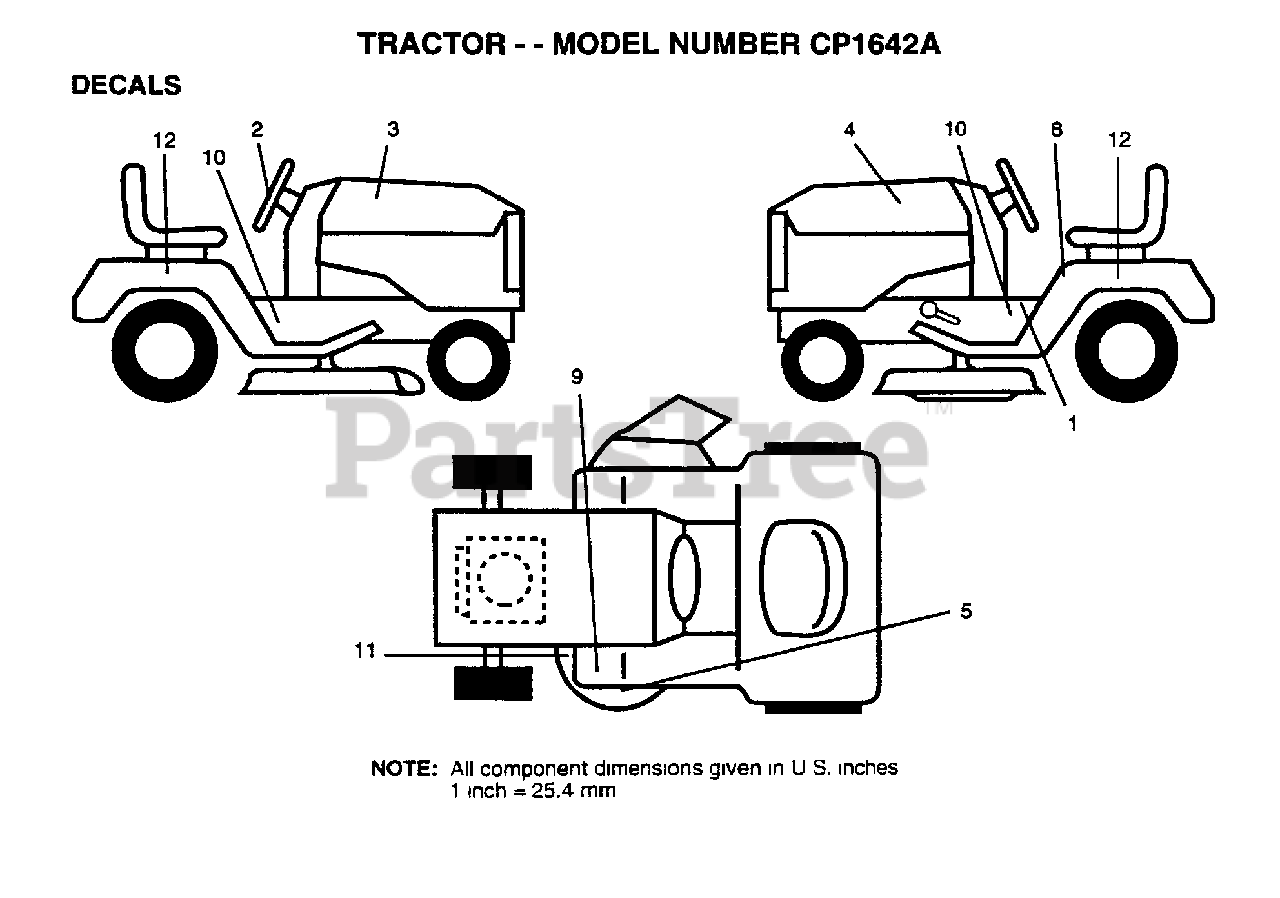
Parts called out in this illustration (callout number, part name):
3	DCL.HD.RH.16HP.CN
4	DCL.HD.LH.16HP.CN
8	DECAL
10	CHASSIS DECAL
11	DECAL
12	DECAL.FEND.QUICK.
